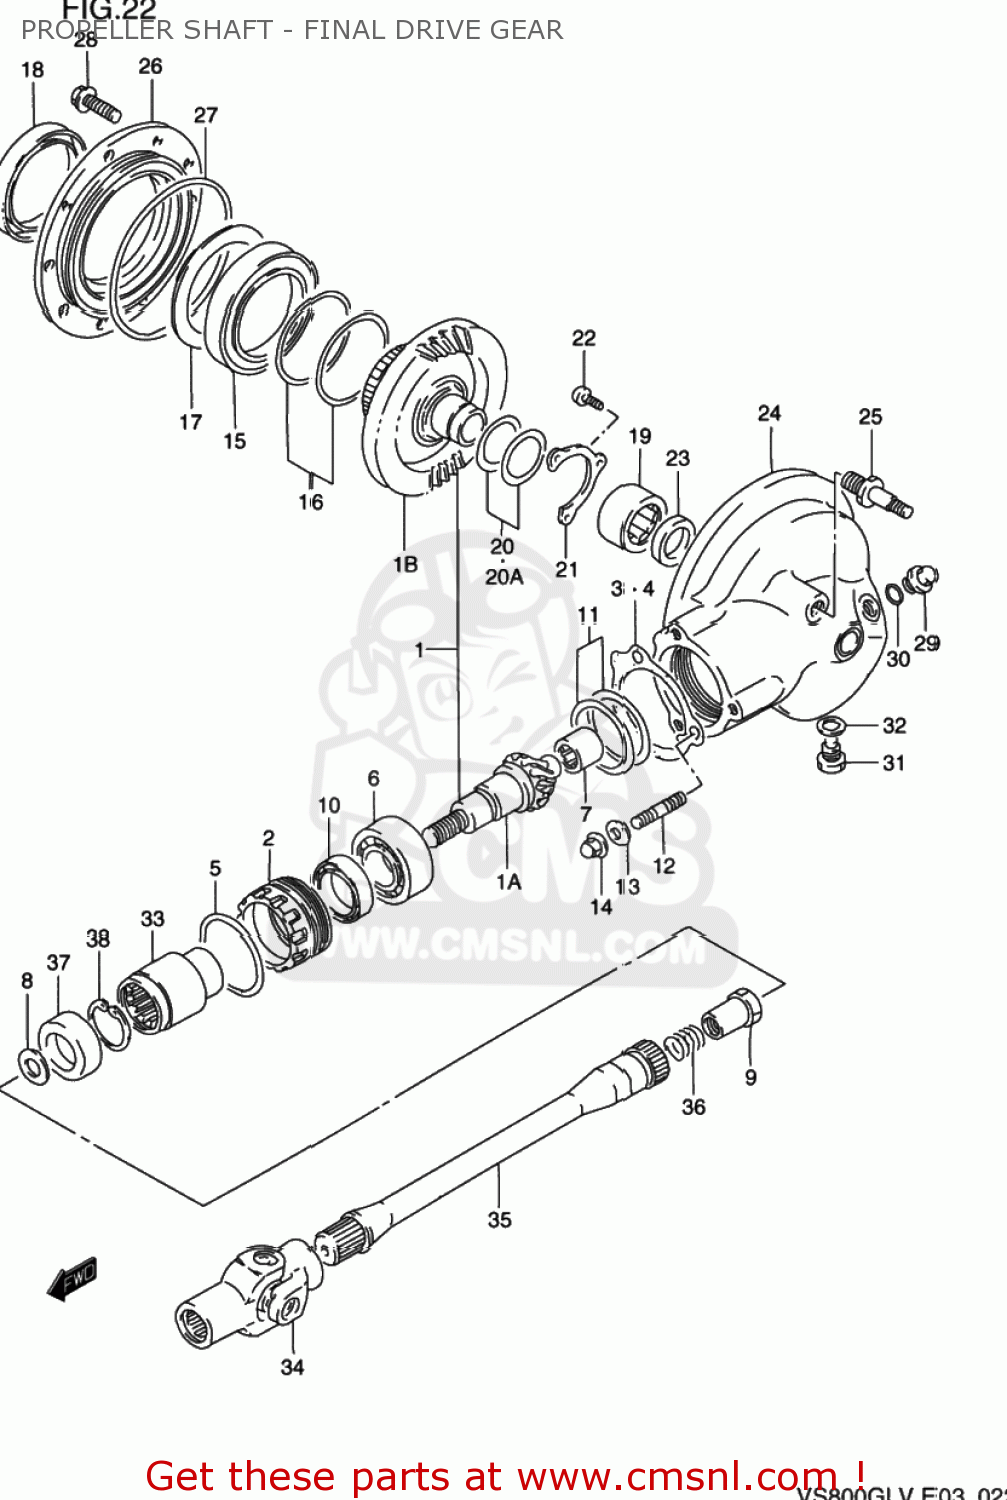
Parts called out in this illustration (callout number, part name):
1	GEAR & CASE SET,FINAL BEVEL
1A	GEAR,FINAL DRIVE BEVEL(NT:11)
1B	GEAR,FINAL DRIVEN BEVEL(NT:34)
2	STOPPER,FINAL DRIVE BEARING
3	PLATE,BEARING STOPPER
4	PLATE,BEARING STOPPER
5	O RING(D:1.9,ID:61.6)
6	BEARING(30X62X23.8)
7	BEARING(17X32X16)
8	WASHER(16X29X4)
9	NUT
10	SEAL,OIL(38X54X6)
11	SHIM SET,FINAL DRIVE GEAR
12	BOLT,STUD
13	WASHER
14	NUT
15	BEARING(70X110X13)
16	SHIM SET,DRIVEN GEAR BEARING
17	PLATE,FINAL DRIVEN BRG OIL
18	SEAL,OIL(70X96X16)
19	BEARING(32X46X17.7)
20	SHIM SET,FINAL DRIVEN GEAR
20A	SHIM SET,FINAL DRIVE GEAR
21	RETAINER,FINAL DRIVEN GEAR BRG
22	SCREW
23	SEAL,OIL(30X42X7)
24	CASE,FINAL
25	BOLT,STUD
26	CASE,FINAL GEAR BEARING
27	O RING(D:3.5,ID:131.6)
28	BOLT
29	PLUG
30	O RING(D:2.4,ID:17.8)
31	PLUG
32	GASKET(14X19.2X2) (NAS)
33	COUPLING,FINAL DRIVE GEAR
34	YOKE COMP,UNIVERSAL JOINT
35	SHAFT,PROPELLER
36	SPRING
37	SEAL,OIL(28.4X48X15)
38	CIRCLIP
